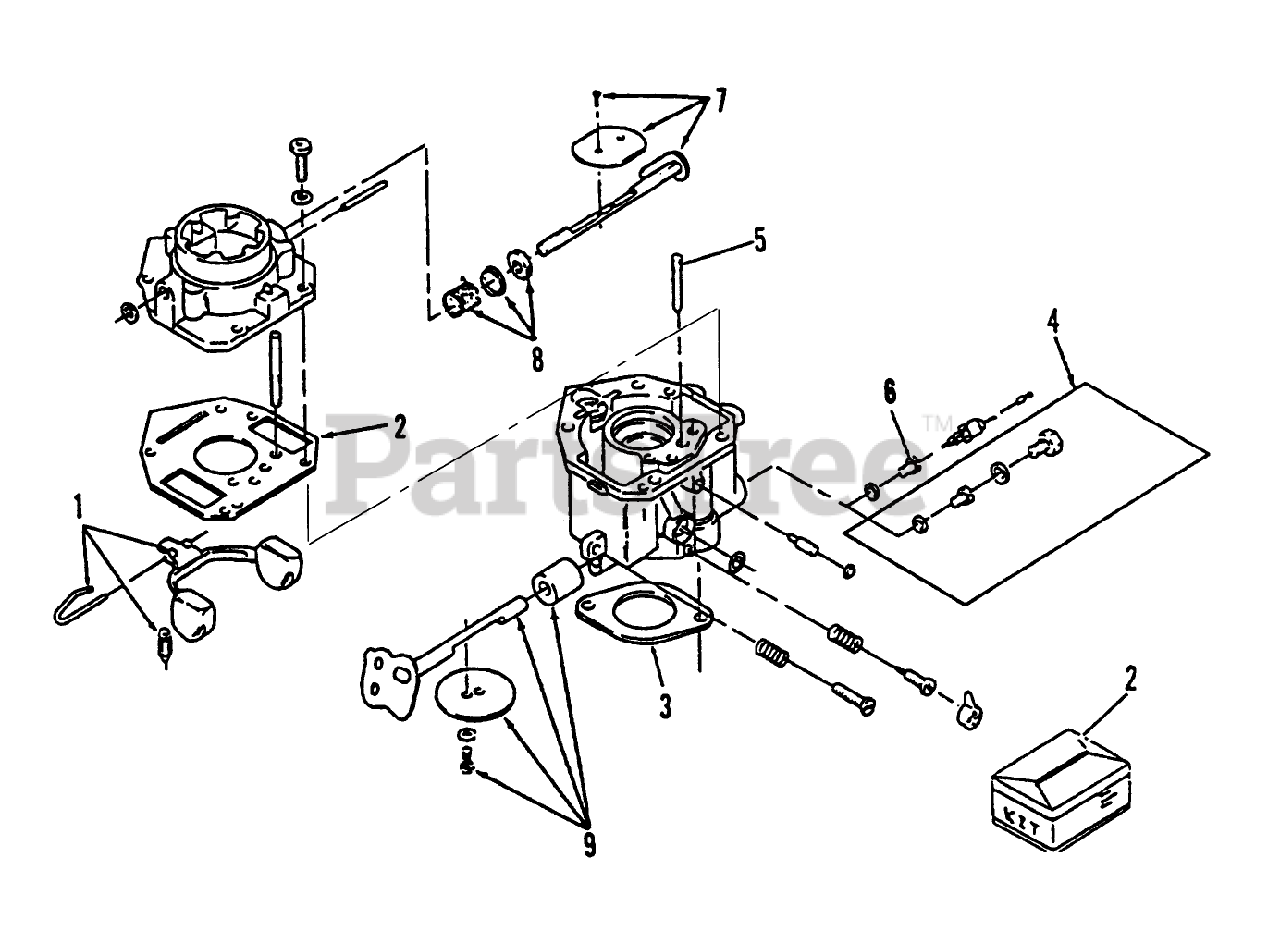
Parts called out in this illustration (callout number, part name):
2	REPAIR KIT
3	GASKET-CARBURETOR
8	CHOKE-LEVER KIT
